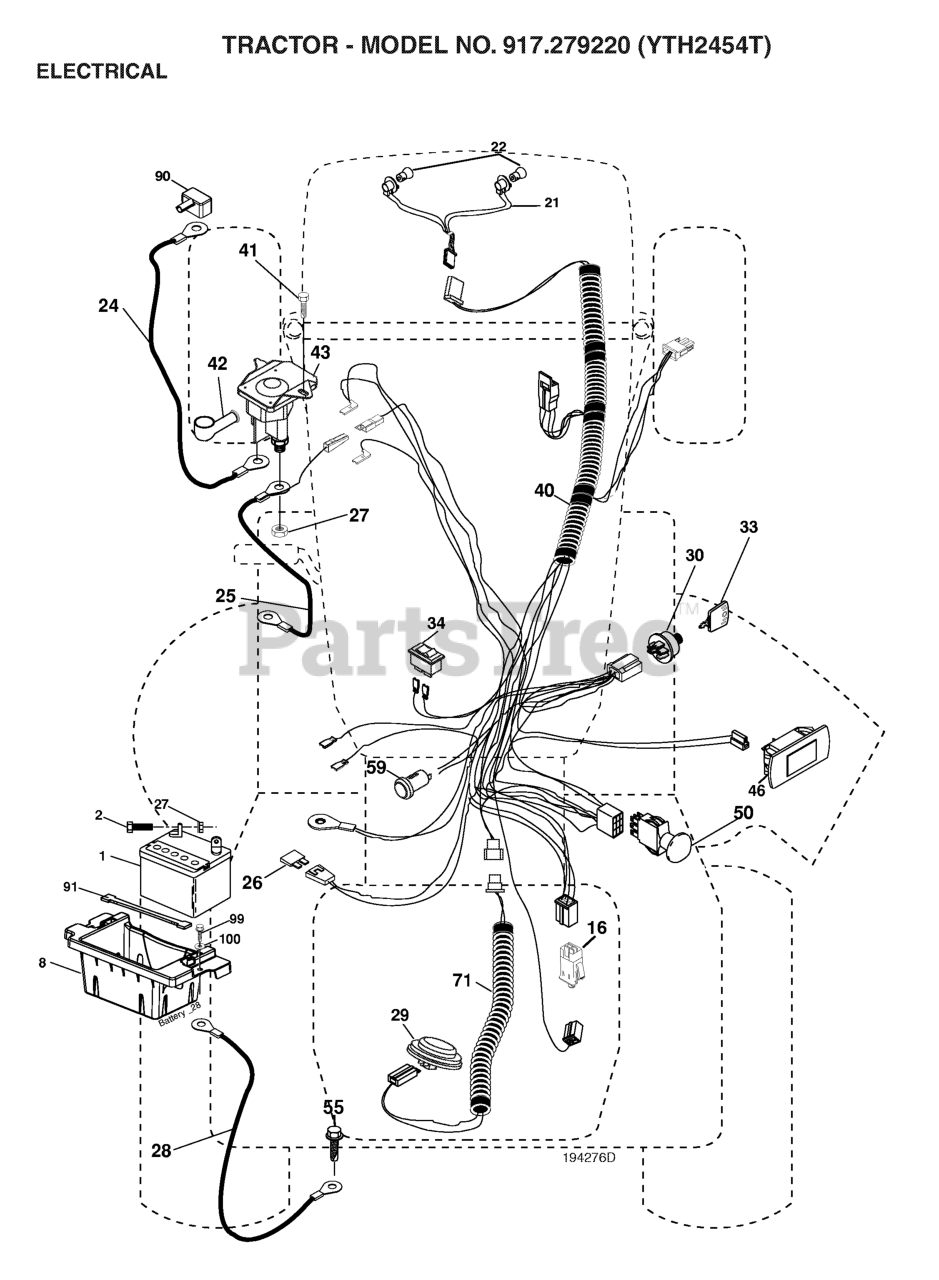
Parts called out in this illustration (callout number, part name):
1	BATTERY 12V .35 AMP
2	BOLT.HEX.1/4.X.3/4.DICHROMATE
8	BOX.BATTERY.MOUNT.FRONT.LT
16	SWITCH INTERLOOK PUSH-IN
21	HARNESS ASSY LIGHT
24	CABLE.BATT.POS.WIRE.TG.DA SOL
25	CABLE.START.RED.17.5".
26	FUSE 20AMP
27	NUT
28	CABLE GROUND 6 GA 21" 90T BLK
29	SWITCH.SEAT.DELTA.OPC.
30	SWITCH.IGN.DELTA.W.LGH.ROS
33	KEY MLD GEN DELTA
40	HARNESS-CHASSIS SUB
41	SCREW
42	TERMINAL COVER
43	SOLENOID.W/BRASS.PLUNGER
46	GAUGE.SERVICEMINDER.HR
50	RP.PTO.SWITCH.8 TERMINAL.BLACK
55	SCREW.THDROL.5/16-18X3/4.TTY
59	OUTLET.12-VOLT
71	HARNESS.IGN.DASH.HUQ/PRED.OUTL
90	COVER TERMINAL
91	STRAP.BATTERY.MOUNT.FRONT(2 2)
99	SCREW HEXWSHR 1/4-20X3/4
100	WASHER
